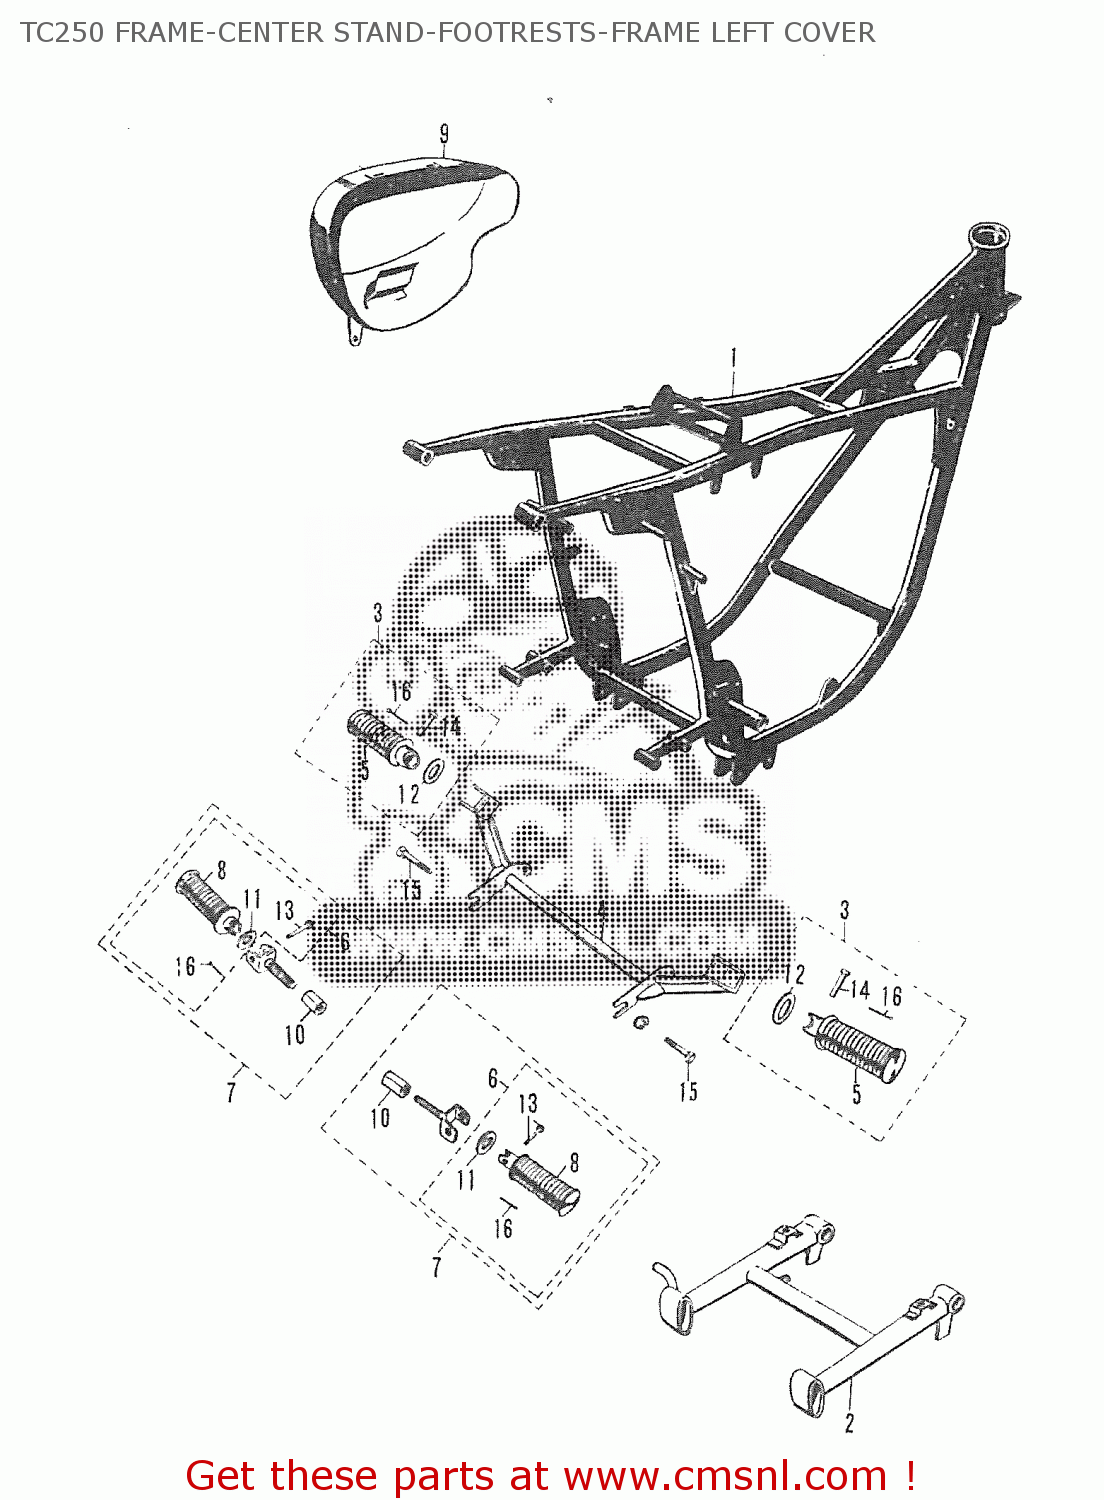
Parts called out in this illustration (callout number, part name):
1	FRAME
2	CENTER STAND
3	FOLDING FOOTREST RUBBER ASS'Y
4	FOOTREST BAR
5	RUBBER,FRONT FOOTREST
6	FOOTREST ASSEMBLY,REAR
7	FOOTREST ASSEMBLY,PILLION
8	BAR,REAR FOOTREST
9	FRAME LEFT COVER
10	NUT
11	WASHER
12	WASHER
13	PIN
14	PIN
15	SMALL HEAD HEXAGON BOLT
16	COTTER PIN
